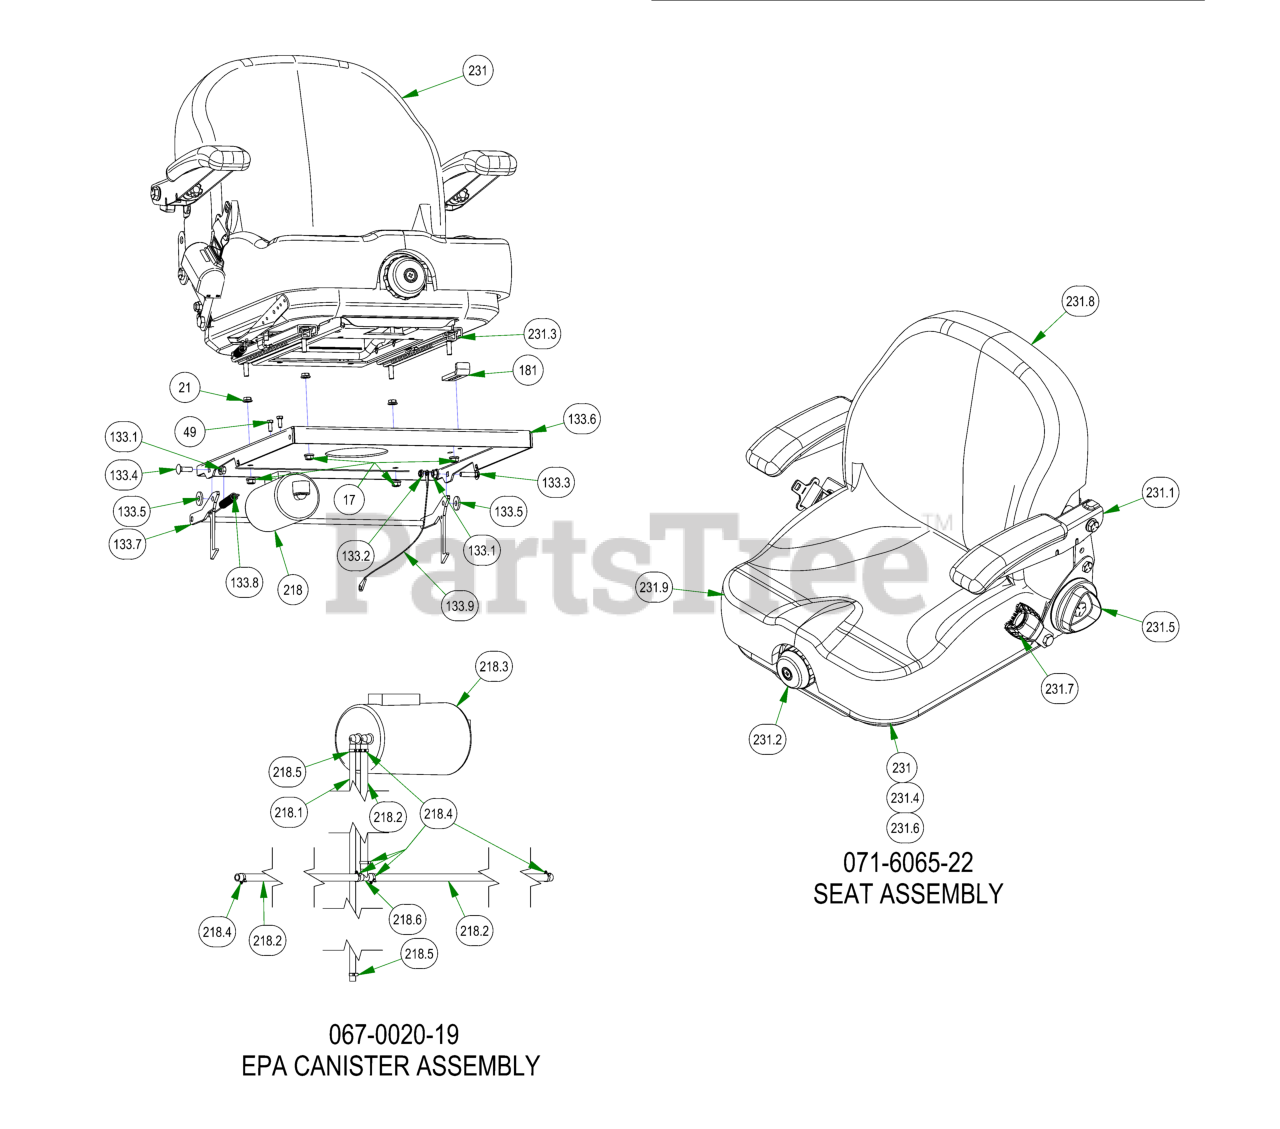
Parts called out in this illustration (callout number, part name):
133	R-SERIES SEAT PLATE ASSEMBLY
133.1	5/16-18 NYLON INSERT FLANGE LOCKNUT ZINC
133.2	5/16-18 NYLON INSERT JAM LOCKNUT ZINC
133.3	5/16-18 X 1-1/4 CARRIAGE BOLT ZINC
133.4	5/16-18 X 1 CARRIAGE BOLT (GR.8) ZINC
133.5	.360 ID X .983 OD X .120 THICK FLAT WASHER NYLON
133.6	R-SERIES SEAT PLATE
133.7	Seat Latch Rod Assembly
133.8	Brake Spring
133.9	Seat Cable
218	2019 Outlaw EPA Cannister Assembly
218.1	3/16" Vinyl Tubing, 66" Long
218.2	1/4" Vinyl Tubing 38" Long
218.3	Carbon Canister
218.4	3/16 Vinyl Clamp
218.5	3/16" Vinyl Hose Clamp
218.6	fuel line T
231	2022 Suspension Seat w/Seatbelt
231.1	Set of Armrests-SS Front Adj
231.2	Weight Adjust Indicator Knob Assy
231.3	4" Single Locking Track Kit
231.4	Delta Plunger Switch - N.O.
231.5	Recliner Adjustment Knob-New
231.6	Bellows w/Hardware
231.7	2" Retractable Belt Kit w/Spacers
231.8	Back Cover for I3M - Recl - Logos
231.9	Cushion Cover Kit for I3M-Logo
